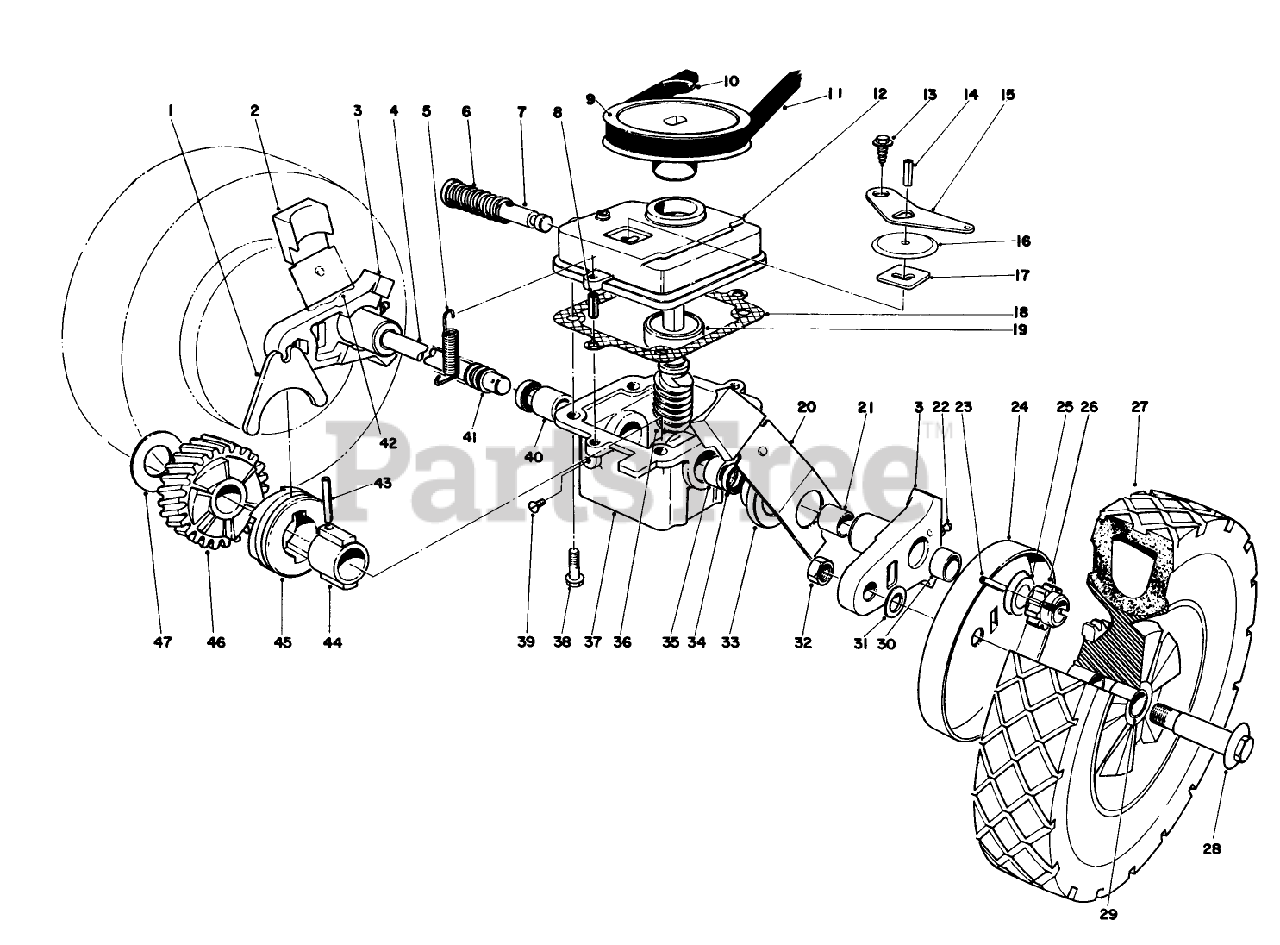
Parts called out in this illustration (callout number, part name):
1	SHIFTER FORK
2	KNOB-ARM
3	PIVOT ARM ASM
4	DRIVE SHAFT (SERVCE)
5	TENSION SPRING
6	SPRING
8	3/16 X 1/2 ROLL PIN
10	PUSH-ON 93-3236
11	BELT-V
14	PIN-ROLL
15	SHIFTER ARM
16	TRANS DUST COVER
17	LATCH PLATE
18	GASKET
21	BUSHING
22	FITTING-GREASE
24	WHEEL COVER
25	WASHER-THRUST
27	WHL/GEAR/TIRE PKG
28	BOLT-WHEEL
29	BUSHING
30	BUSHING
31	WASHER
33	End Cap
35	Bushing
36	WORM SHAFT & GEAR SET
37	GEAR CASE ASM
39	NYLON SCREW
41	COVER-SHAFT, DRIVE
42	SPRING ARM ASM SP RH
43	COIL PIN
44	SLEEVE
45	CLUTCH JAW
46	Helical Gear
47	THRUST WASHER
